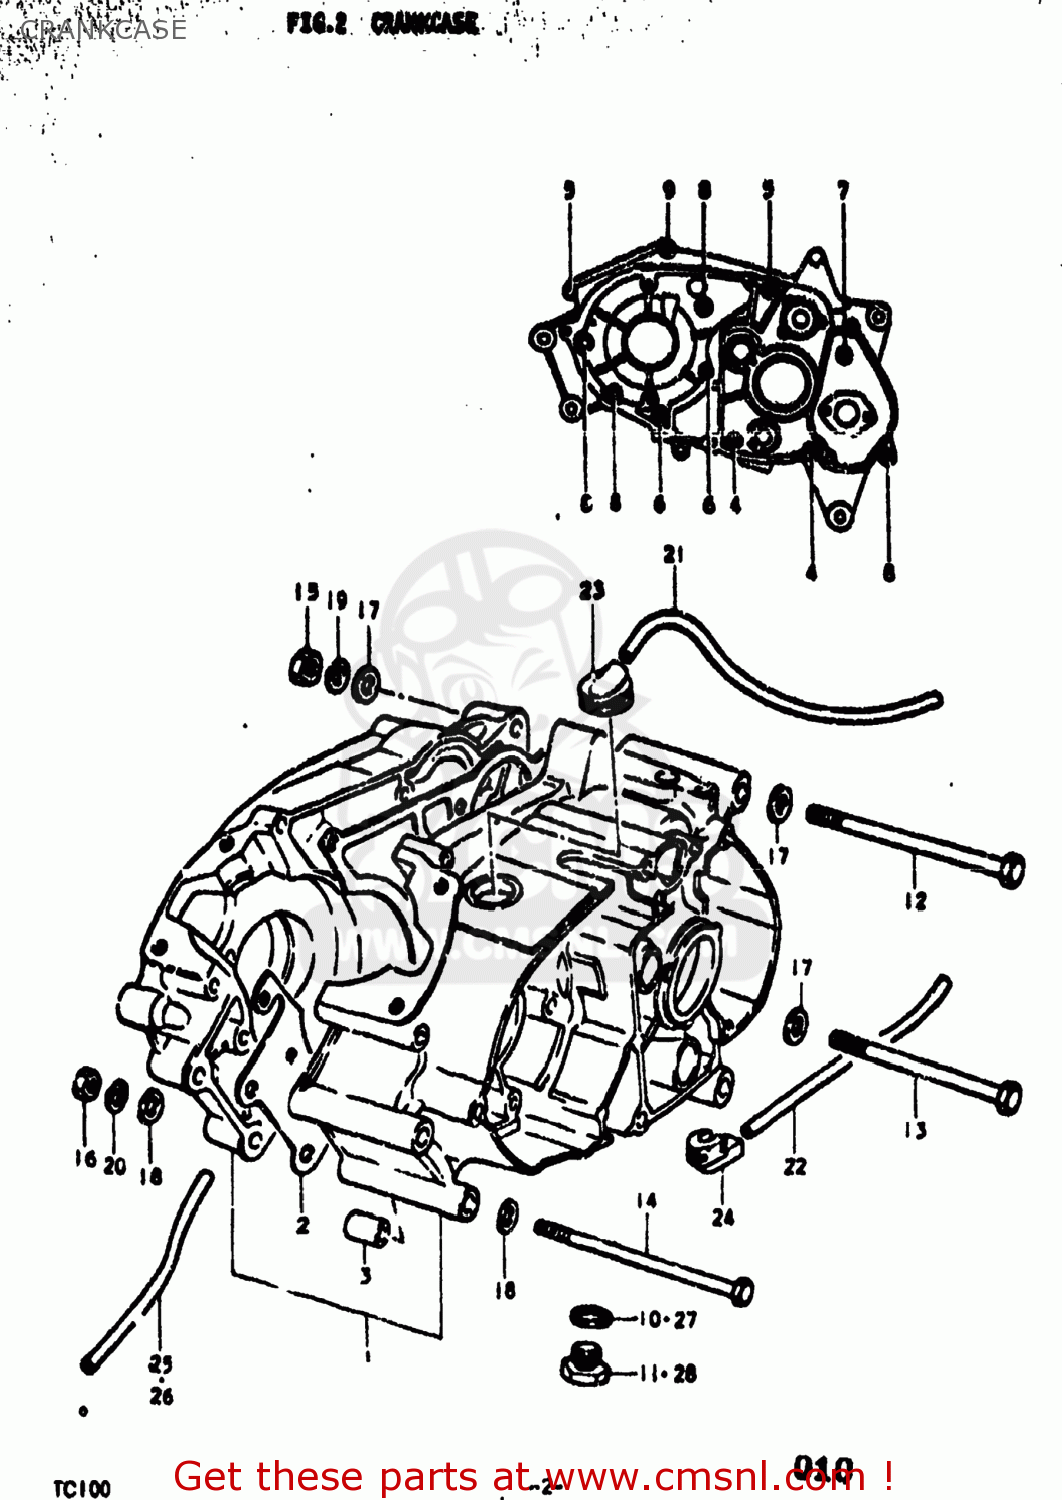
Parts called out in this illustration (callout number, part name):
1	CRANKCASE SET
2	GASKET,CRANKCASE (MCA)
3	PIN
4	SCREW 6X80
5	SCREW 6X70
6	SCREW
7	SCREW
8	SCREW
9	SCREW (6X35)
10	GASKET(10X14X3.6) (NAS)
11	PLUG
12	BOLT 10X120
13	BOLT
14	BOLT
15	NUT
16	NUT
17	WASHER
18	WASHER
19	LOCK WASHER
20	LOCK WASHER
21	HOSE
22	HOSE
23	GROMMET
24	GROMMET
25	HOSE
26	HOSE
27	GASKET(14X19.2X2) (NAS)
28	PLUG
